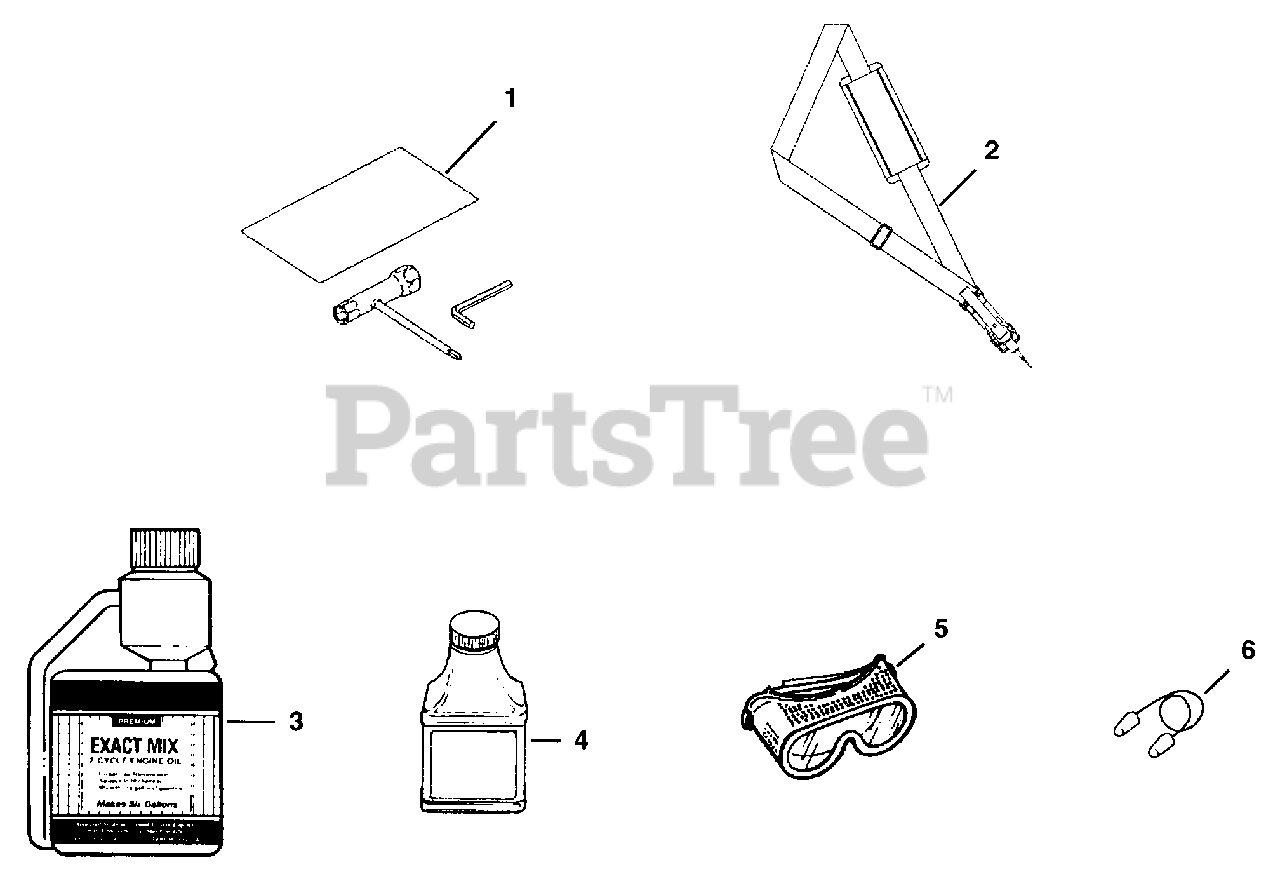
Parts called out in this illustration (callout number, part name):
1	TOOL KIT
3	EXACT MIX(TM) (16 oz.)
4	EXACT MIX(TM) (2.6 oz.)
6	EAR PLUGS
7	DECAL KIT
